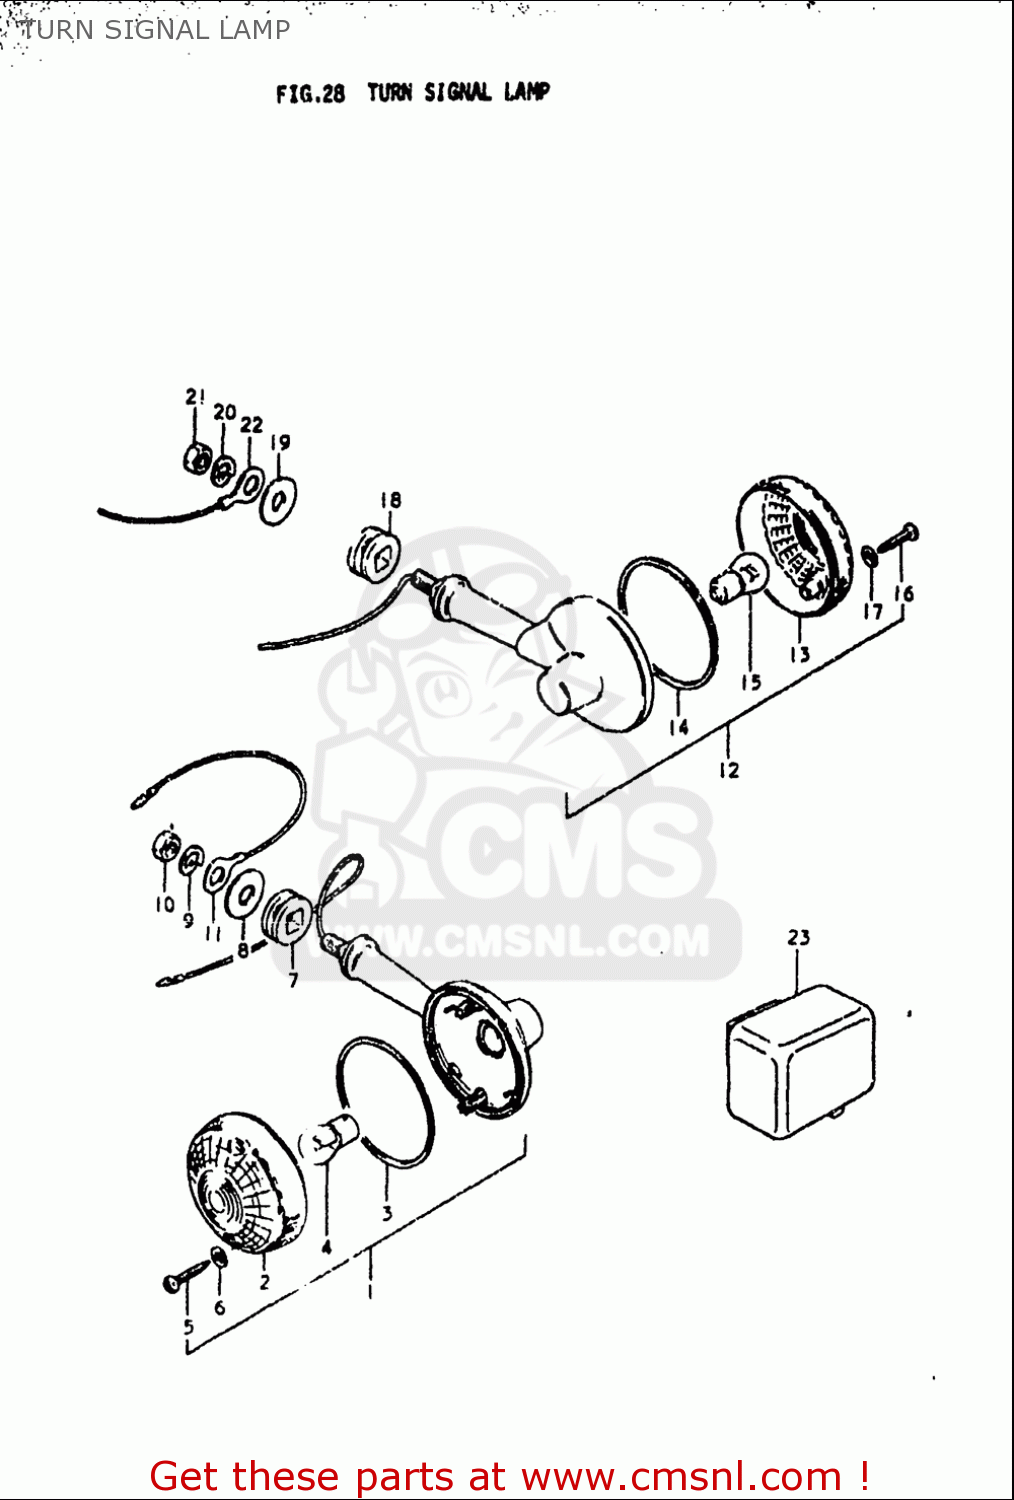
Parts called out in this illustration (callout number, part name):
1	LAMP ASSY,RR TURNSIGNAL
2	LENS
3	GASKET (NAS)
4	BULB(12V23W,STANLEY,A4577A)
5	SCREW
6	GASKET (NAS)
7	CUSHION
8	WASHER (8.5X30X2.3)
9	WASHER,LOCK
10	NUT
11	LEAD WIRE,EARTH
12	LAMP ASSY,RR TURNSIGNAL
13	LENS
14	GASKET (NAS)
15	BULB(12V23W,STANLEY,A4577A)
16	SCREW
17	GASKET (NAS)
18	CUSHION
19	WASHER (8.5X30X2.3)
20	WASHER,LOCK
21	NUT
22	WIRE,REAR TURN SIGNAL EA
23	RELAY ASSY,TURNSIGNAL
